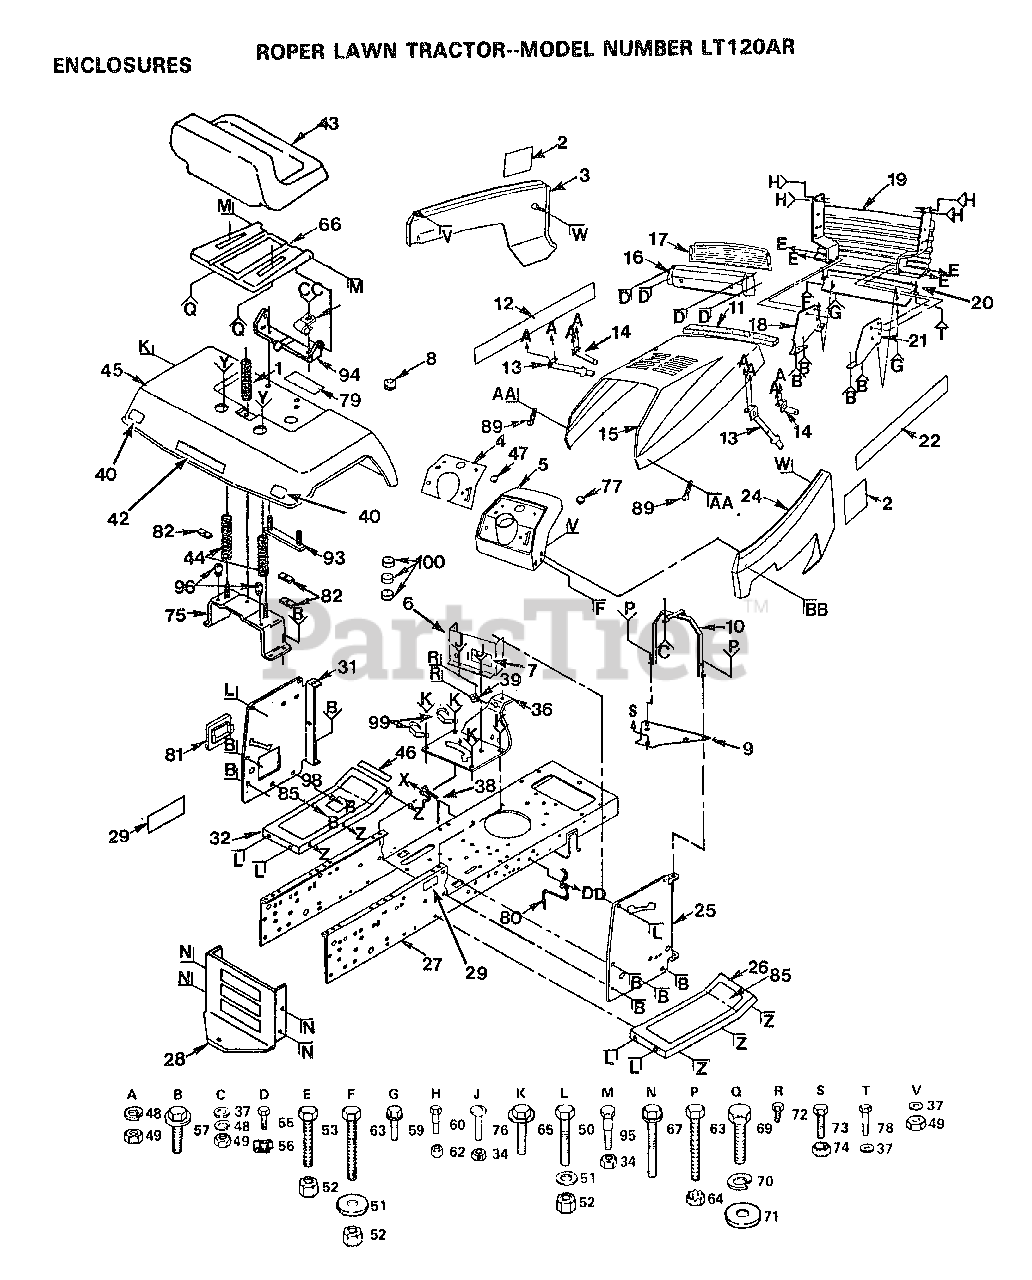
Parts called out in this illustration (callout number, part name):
5	DASHBOARD LT
6	DASH ASSY LT
8	GROMMET T
10	SUPPORT ASSY LT
11	FOAM-STRIP LT
17	LENS LT
18	SUPPORT-GRILL LT
25	PANEL DASH RH YT
31	PANEL DASH HYT
37	WASHER PM
40	REFLECTOR-TAIL YT
47	PLUG-DASH T
51	WASHER
53	BOLT
56	"""J"" FASTENER LT"
57	SCREW
59	SCREW
60	BOLT T
64	NUT
65	SCREW LT
67	SCREW
69	BOLT
71	WASHER
73	BOLT
76	SCREW
77	PLUG BUTTON T
78	SCREW HEX CRT
82	"CLAMP, SPRING LT"
85	PAD FOOTREST T
96	NUT-PUSH YT
99	CLIP T
